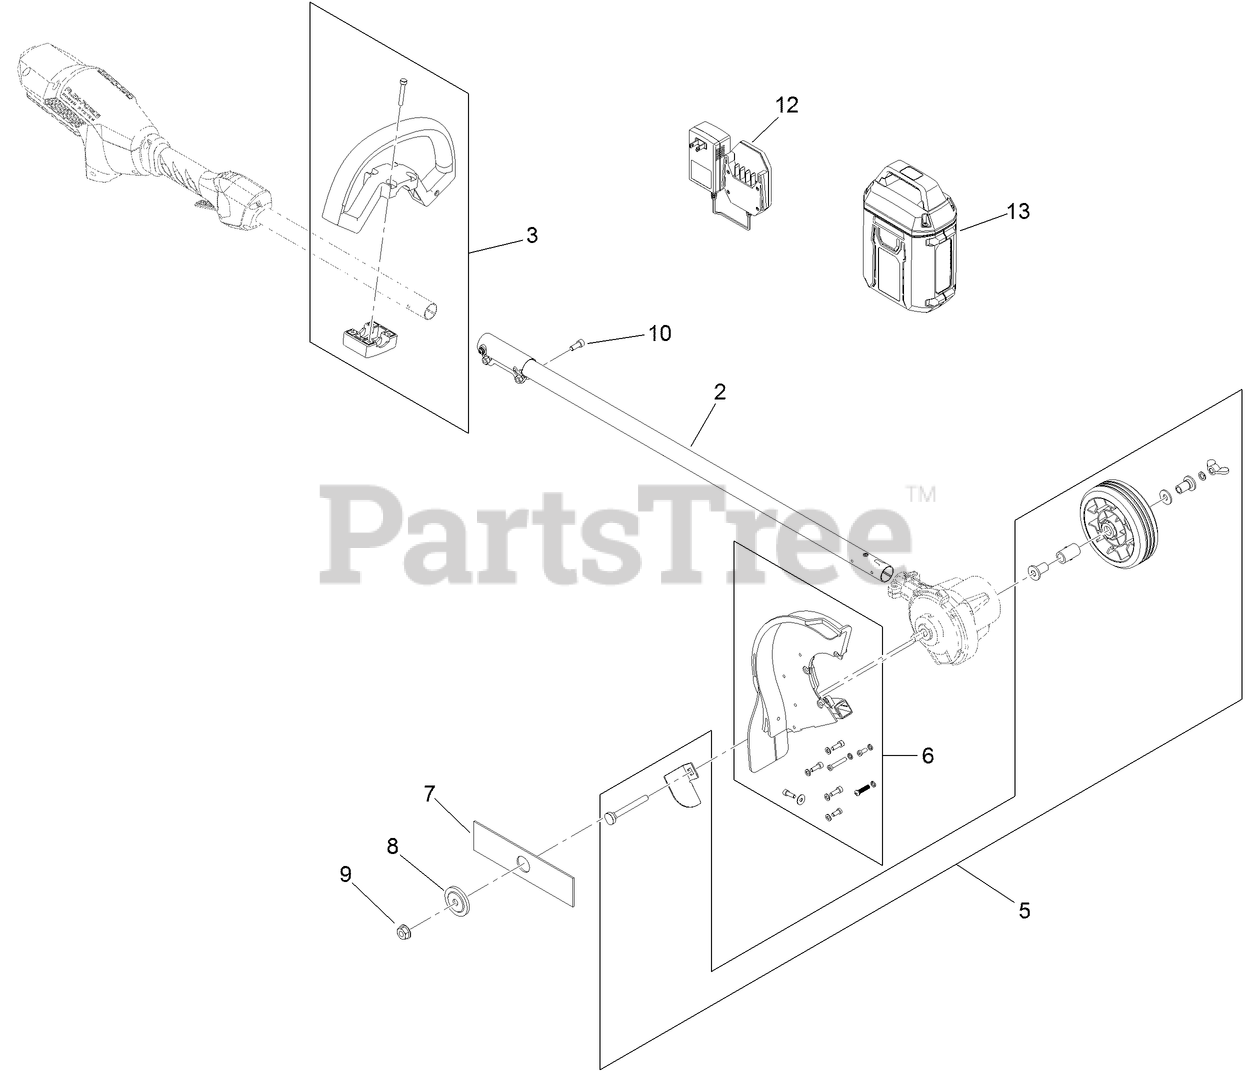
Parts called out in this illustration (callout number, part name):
2	SHAFT ASM
3	HANDLE-TRIMMER
5	WHEEL ASM
6	GUARD ASM
8	WASHER
10	SCREW-ROD
12	CHARGER-BATTERY, 60V 1 AMP
13	BATTERY-60V 2.0AH
